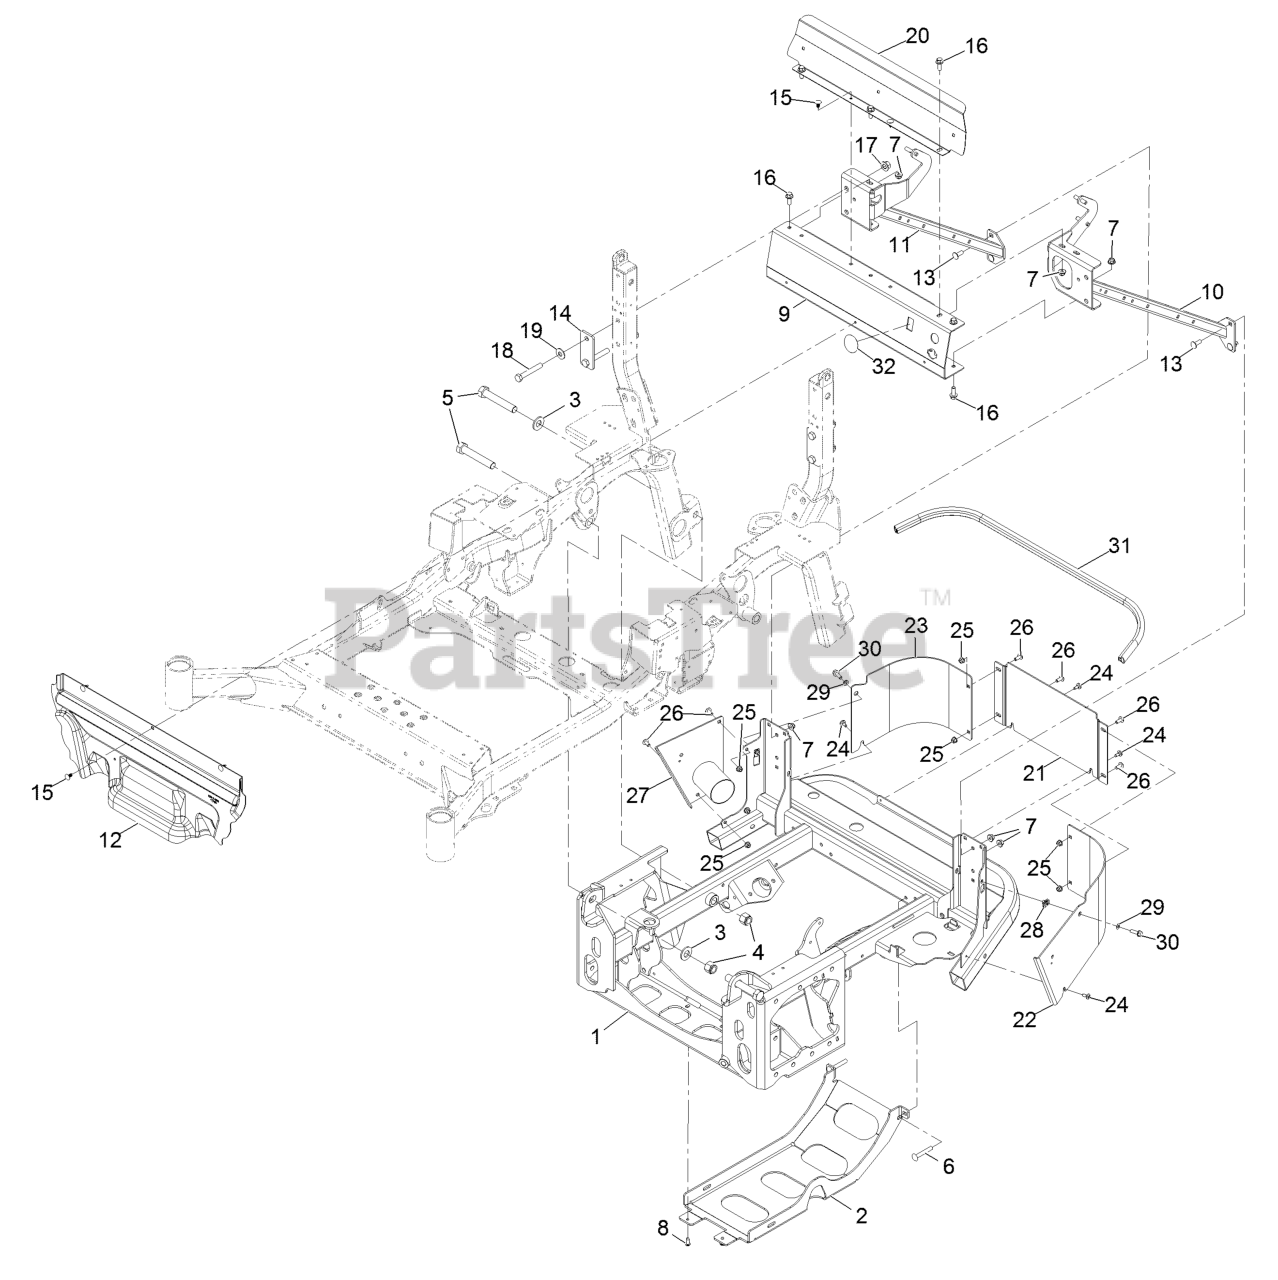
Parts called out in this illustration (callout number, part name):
1	Frame-Power
2	Plate-Skid
3	Washer-Spring Disc 3/4
4	Nut-Nyloc 3/4-10
5	Screw-HH
6	Bolt-Carriage 3/8-16 X 2 1/2
7	Nut-Nyloc 3/8-16 Flg
8	Screw-Button Head 5/16-18 X .725 Tf
9	Channel-Cross
10	Brace-ROPS, LH
11	Brace-ROPS, RH
12	Panel-Deflector, Heat
13	Bolt-Carriage 3/8-16 X 1
14	Plate-Spacer
15	Plug-Plastic
16	Screw-HHF
17	Nut-Lock 1/2-13
18	Screw-HH
19	Washer, Spring Disc 1/2
20	Shield-Air
21	Plate-Bumper, Center
22	Plate-Bumper, LH
23	Plate-Bumper, RH
24	Screw-1/4-20 X 1/2 Tf Torx Plus
25	Nut-Nyloc 5/16-18 Flg
26	Screw-Truss HD 5/16-18 X 3/4 Torx Plus
27	Plate-Exhaust
29	Washer-Belleville
30	Screw-HH Flg 5/16-18 X 1
31	Seal-Bulb
32	Decal-Cover
